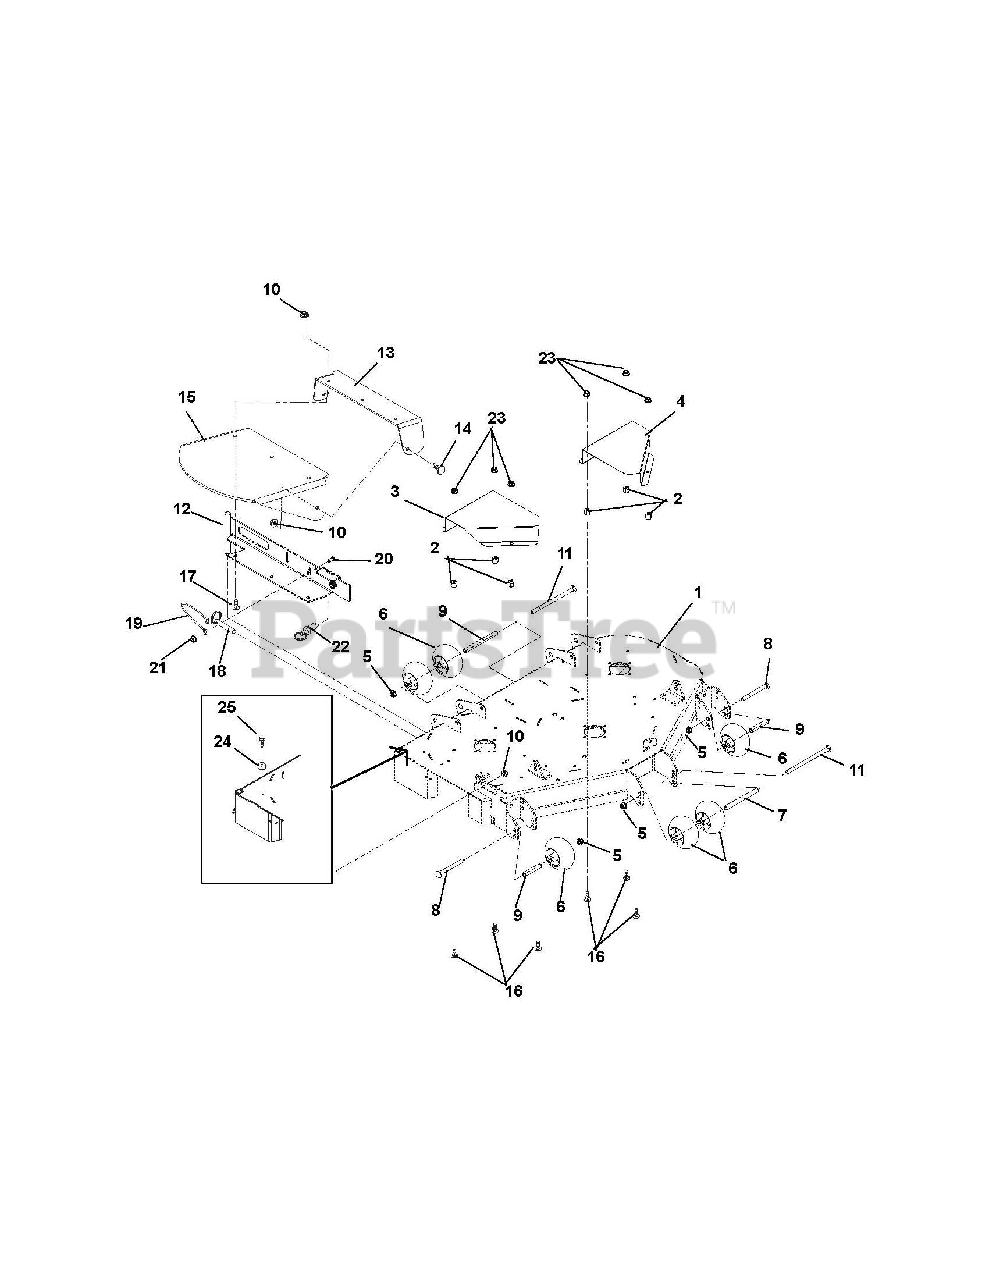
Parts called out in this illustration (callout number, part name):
1	44" Side Discharge Deck Weldment
2	Nut, Heavy Hex .38-16
3	Guard, 44-52 RH Spindle Sheave
4	Guard, 44-52 LH Spindle Sheave
5	Nut .50-13 Nyloc Flange
6	Anti-Scalp Wheel
8	Bolt, Round Head Square Neck .50-13 x 5.00
9	Spacer, .510 x .625 x 3.35
10	Nut, .38-16 Nyloc Flange
11	Bolt, Round Head Square Neck .50-13 x 8.50
12	Weldment, Discharge Chute Support
13	Rubber Discharge Chute Support
14	Bolt, Round Head Square Neck .38-16 x 1.00 Grade 5
15	Chute, Rubber Discharge
16	Bolt, Hex Head .38-16 x 1.25 Grade 5
17	Bolt, Round Head Square Neck .38-16 x 1.25 Grade 5
18	Pin, Spring Ball .375 x 1.50
19	Cable, 6.0 Lanyard
20	Bolt, Hex .25-20 x .75
21	Nut, Locking Top Flange .25-20
22	Pull Pin
23	Nut, Flange .375-16
24	BUMPER, RECESSED 1.50 X .63 W/ .31
25	SCREW, TAPPING .31-18 X .75 HEX WASHER HEAD THREAD
